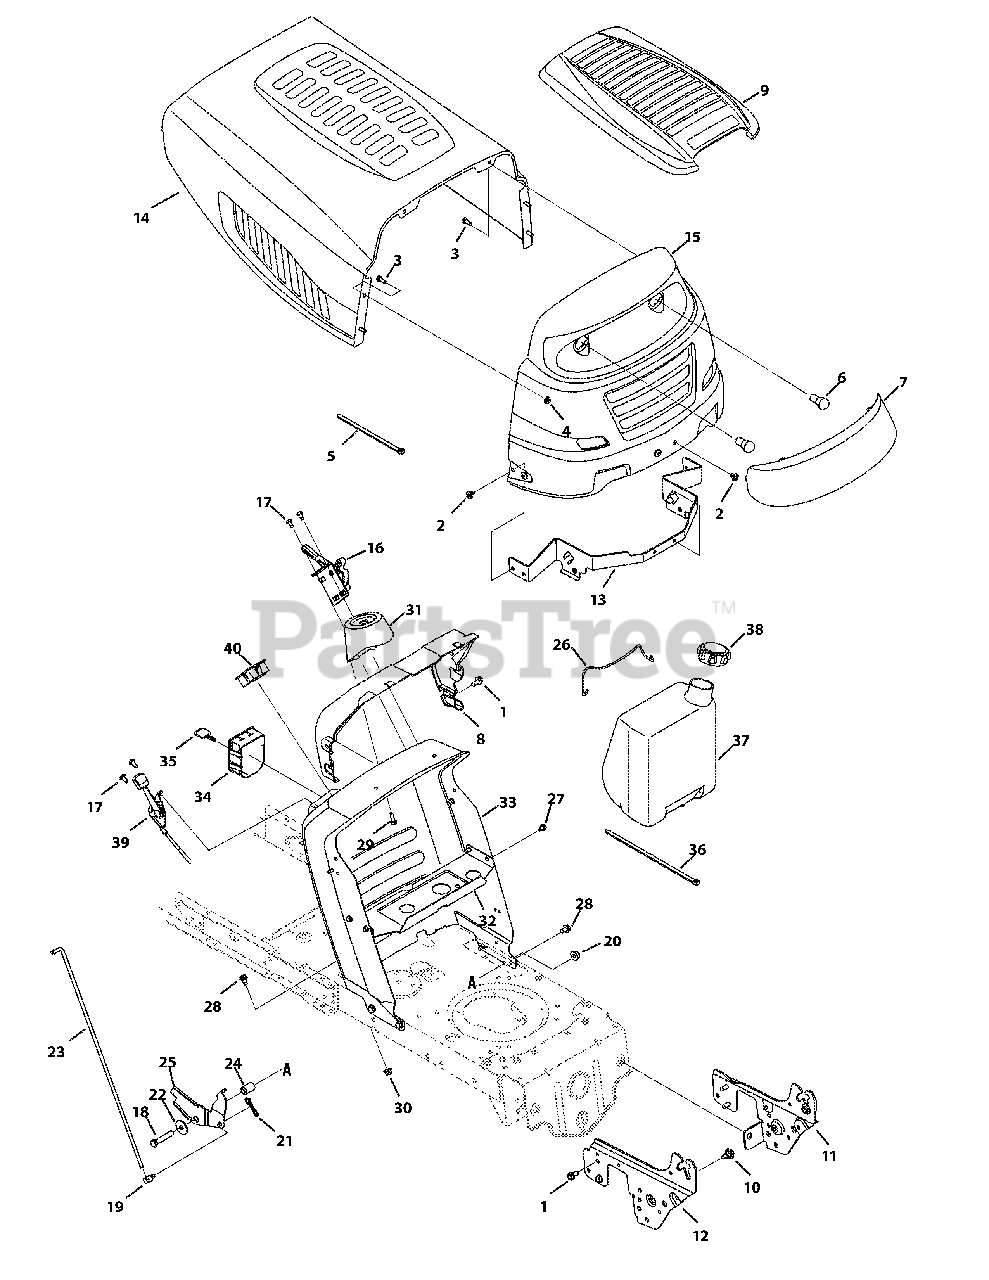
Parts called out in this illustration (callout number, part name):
1	Screw 5/16-18 x .750
2	Screw 5/16-18 x .375
3	Hex Screw 1/4-20 x .620
4	Flanglock Nut 1/4-20
5	Cable Tie
6	Miniature lamp 12V socket
7	Grill Lens
8	Dash Collar
9	Hood cover
10	Shoulder Screw .43 x .29
11	Suppport Bracket LH
12	Suppport Bracket RH
13	Hood pivot bracket
14	Hood - 5 Style - Grey
14	Hood - 5 Style - Black Jack
14	Hood - 1 Style - Red
15	Grill - Grey
15	Grill - Black Jack
15	Grill - Red
16	Hydro Control Assembly
17	Screw 1/4-20 x .500
18	Hex Screw 3/8-16 x 2.00
19	Ferrule Adjust
20	Flang lock Nut 3/8-16
21	Cotter Pin, Bow Tie
22	Flat Washer .411 x 1.25 x .100
23	Control Rod, Speed Selector
24	Flang Spacer .390 x .671 x 1.095
25	Transmission Speed Latch
26	Battery Rod
27	Hex Screw Washer 1/4-20 x .500
28	Screw 5/16-18 x .625
29	Hex Screw 1/4-15 x .750
30	Flanglock Nut 5/16-18
31	Support Shaft
32	Gas Tank Support Bracket
33	Dash, RMC - Black Jack
33	Dash, RMC - Powder Black
33	Dash, RMC/Amp Meter/Choke
34	Key Switch Module
35	Key
36	Cable Tie
37	Fuel Tank, 1.5 Gallons
38	Fuel Cap
39	Throttle/Choke Control Cable
40	Ammeter Monitor Indicator
